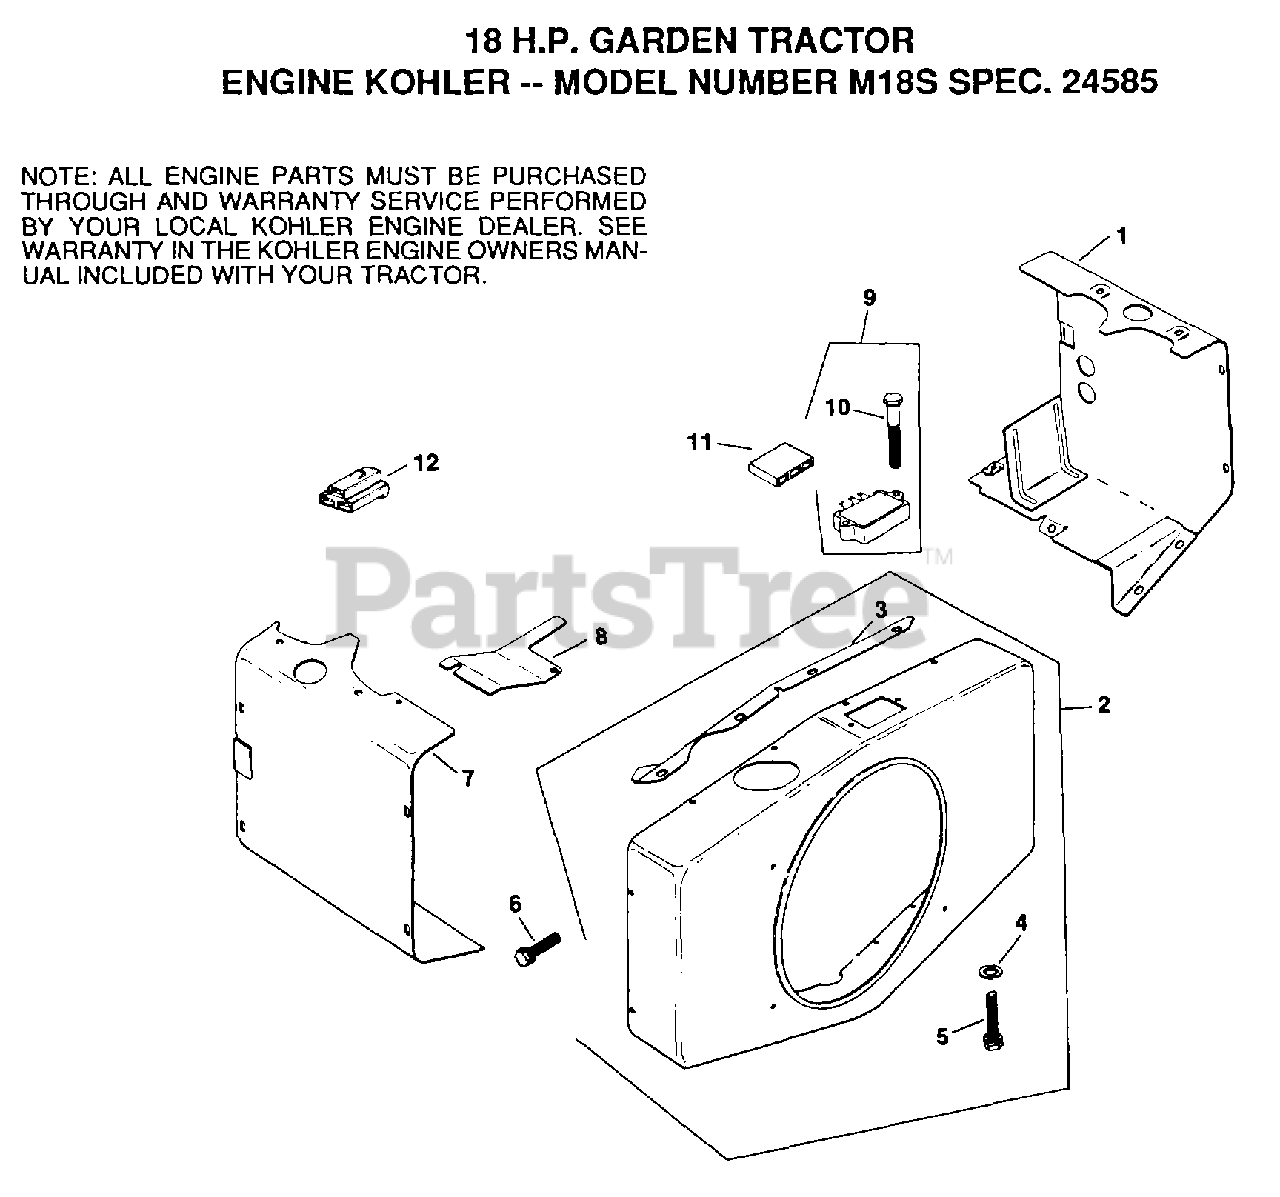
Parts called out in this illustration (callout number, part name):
2	KIT, BLOWER HOUSING
6	SCREW
7	BATTLE, #2 CYLINDER HEAD
8	BAFFLE, #2 CYLINDER TOP
10	SCREW
11	CONNECTOR
12	CONNECTOR
